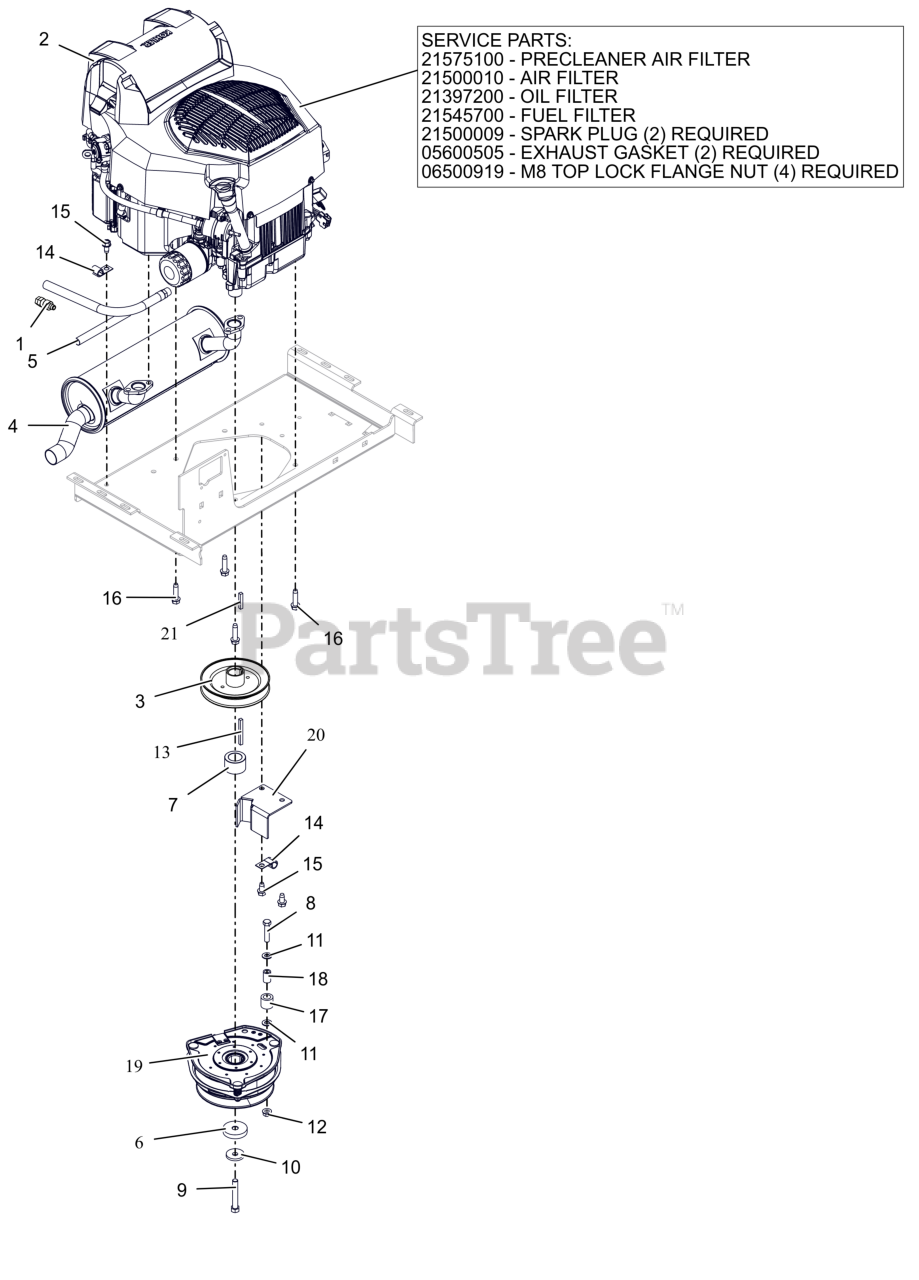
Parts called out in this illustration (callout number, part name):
1	HOSE, OIL DRAIN
2	ENGINE, KOHLER ZT740 CONFIDANT
2	PRECLEANER AIR FILTER
2	AIR CLEANER, KOHLER CONFIDANT
2	FILTER, OIL - KOH CV20
2	FILTER-FUEL KOHLER COURAGE PRO
2	PLUG, SPARK KOHLER
2	GASKET, MUFFLER KOHLER TWIN
2	NUT-LK-TOP-FLG M8 ZCC
3	WLDMT, TRANSAXLE DRIVE PULLEY
4	MUFFLER, ZT730/ZT740
5	SLEEVE, THERMAL 6"
6	SPACER, .450X2.00X.396
7	SPCR, 1.125 x 1.750 x 1.147
8	BLT, HEX .38-16X1.75 G5 ZCC
9	BLT, HEX 0.4375-20X2.75 G8 ZCC NT
10	WASHER, 7/16" SPRING DISK
11	WSHR,FLT .406X.812X.065 ZCC
12	NUT-LK-CTR-FLG .375-16 GF ZCC
13	KEY-SQ .25 X 2.50 X .25 SAE
15	SCR,TAP .375-16X.75 HWH TR ZCC
16	SCR-TAP .38-16X1.50 HWH ZCC
17	BUMPER,RUBBER .62X1.0X.88 LG
18	BUSH.,S.391X.622X.950 ST
19	CLUTCH, OGURA GT3.5-AR04
20	WLDMT, CLUTCH STOP (BLACK)
21	KEY-SQ .25 X 1.50 X .25 SAE
